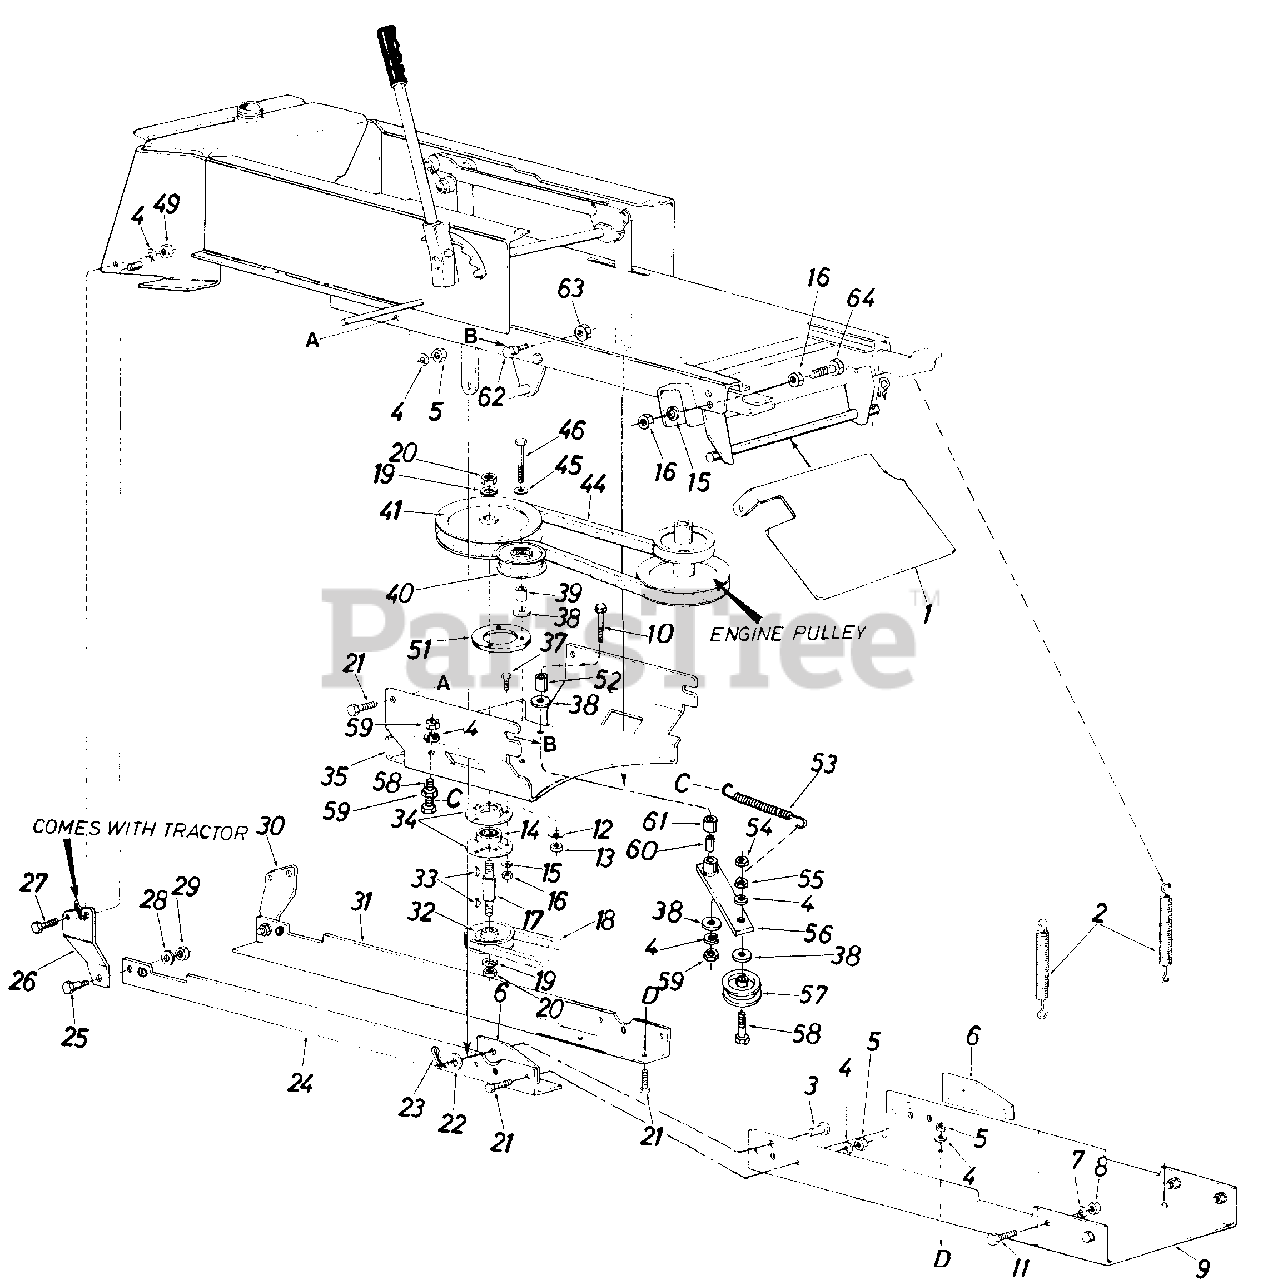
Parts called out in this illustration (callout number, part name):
1	Guide Bracket
2	Helper Spring
3	Clevis Pin
4	L.-Wash. 3/8" I.D.*
5	Hex L.-Nut 3/8-24 Thd.
6	Attaching Plate
7	L.-Wash. 1/2" I.D.*
8	Hex L.-Nut 1/2-20 Thd.
9	Front Support Channel
10	Hex Bolt 3/816x 3.75" Lg.
11	Hex Bolt 1/220x 1.25" Lg.*
12	Belleville Wash. 3/8" I.D.
13	Hex L.-Nut 3/8-16 Thd.
14	Ball Bearing
15	L.-Wash. 5/16" I.D.*
16	Hex Nut 5/16-18 Thd.*
17	Spindle
18	"V"-Belt 1/2" x 88" x 2 [ (Kevlar)
19	L.-Wash. 5/8" I.D.*
20	Hex Jam Nut 5/8-11 Thd.
21	Hex Bolt 3/8-24 x 1.00" Lg.*
22	Flat Washer
23	Internal Cotter Pin
28	Fl.-Wash. .44" I.D. x 1.38" O.D. x .130
29	Hex L.-Nut 7/16-24 Thd.
30	Rear Hanger Brkt. - L.H.
33	#6 Hi-Pro Key 3/16 x 5/8" Dia.
34	Bearing Housing
35	Supporting Bracket
37	Hex Sems Bolt 5/16-18 x 1.00" Lg.*
38	Fl.-Wash. .38" I.D. x 1.00" O.D. x .135
39	Spacer.38" I.D. x .62" O.D.
40	Fl.-Idler Pulley
41	Upper Drive Pu I ley
44	"V"-Belt 1/2" x 49.8" Lg.
45	F l.-Wash.
46	Hex Bolt 3/8-16 x 2.50" Lg.*
49	Hex Nut 3/8-16 Thd.*
53	Extension Spring .54" O.D. x 4 .75" Lg.
54	Hex Cent. L.-Nut 3/8-16 Thd.
55	Hex Jam Nut 5/8-11 Thd.
56	Idler Arm Ass'y.
57	Idler Pulley
58	Hex Bolt 3/8-16x 2.25" Lg.
59	Hex Jam Nut 3/8-16 Thd.
60	Spacer .377" I.D. x .60" O.D. x.830" Lg.
61	Spacer.380" I.D. x .630" O.D. x.565" Lg.
62	Shoulder Bolt.498 Dia. x.340
63	Hex Cent. L.-Nut 3/8-16 Thd.
64	Hex Bolt 5/16-18 x 1.50" Lg.*
